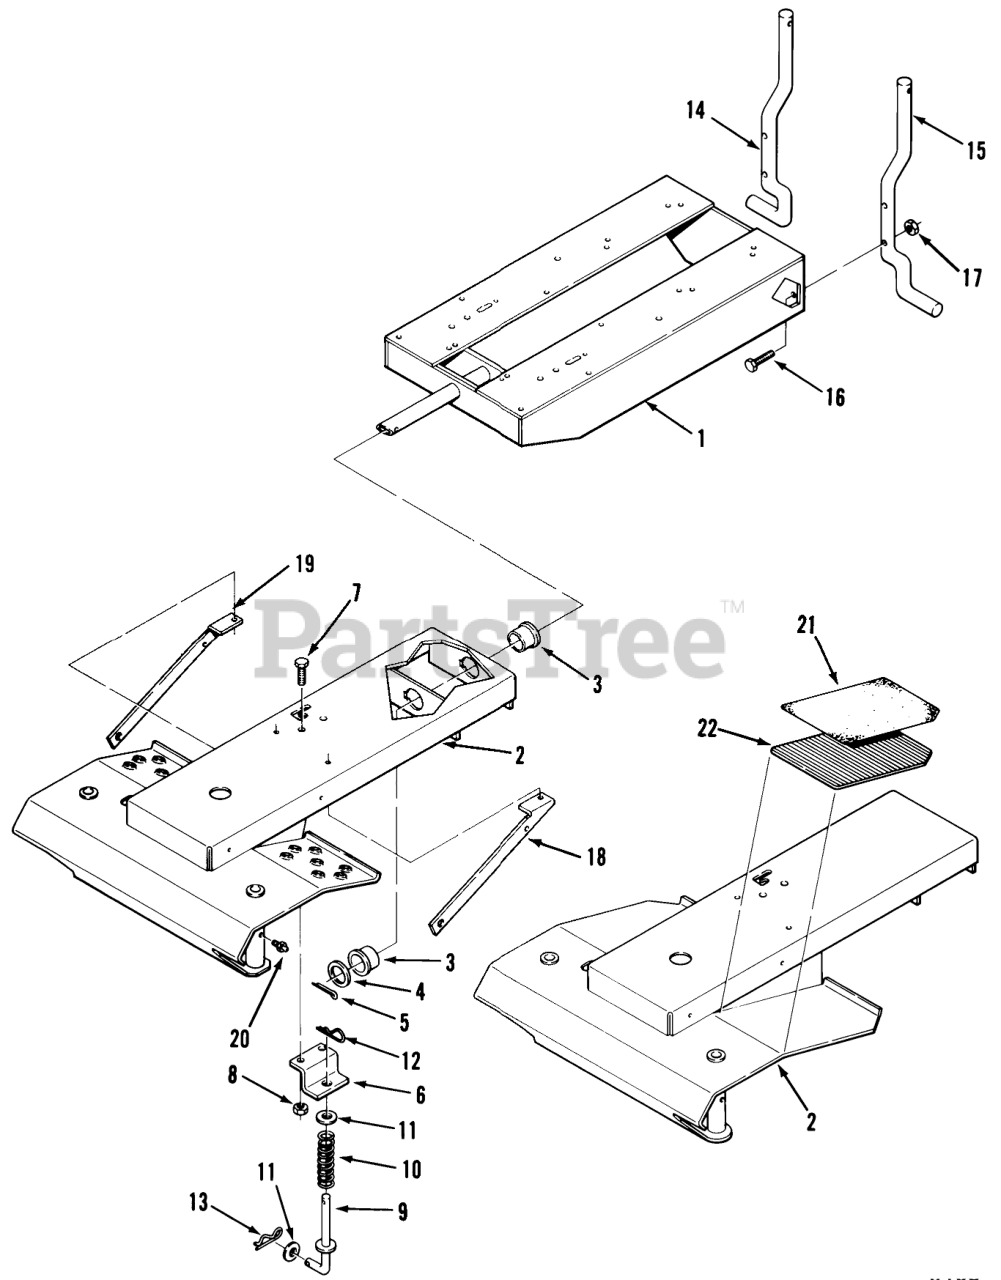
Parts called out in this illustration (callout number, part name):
1	Rear Frame Assy
1	Rear Frame Ass-y 108-3, 108-5, 111-5
2	Front Frame Assy
2	ASSY FRONT FRAME R
3	BEARING FLANGE
4	WASHER
5	Pin-Cotter
6	BRACKET R
7	Bolt
8	NUT
9	ROD ASSY R
10	SPRING-COMPRESSION
11	Washer
12	Hairpin Cotter
13	Hairpin
14	REAR ROD RH B
15	REAR ROD LH B
16	BOLT 5/16-18X1 1/2
17	Nut
18	ASSY BRACE AXLE LH
19	ASSY BRACE AXLE RH
20	Grease Zerk
21	PAD FOOTREST RH
21	PAD FOOTREST LH
22	PAD FOOTREST RH
22	PAD FOOTREST LH
